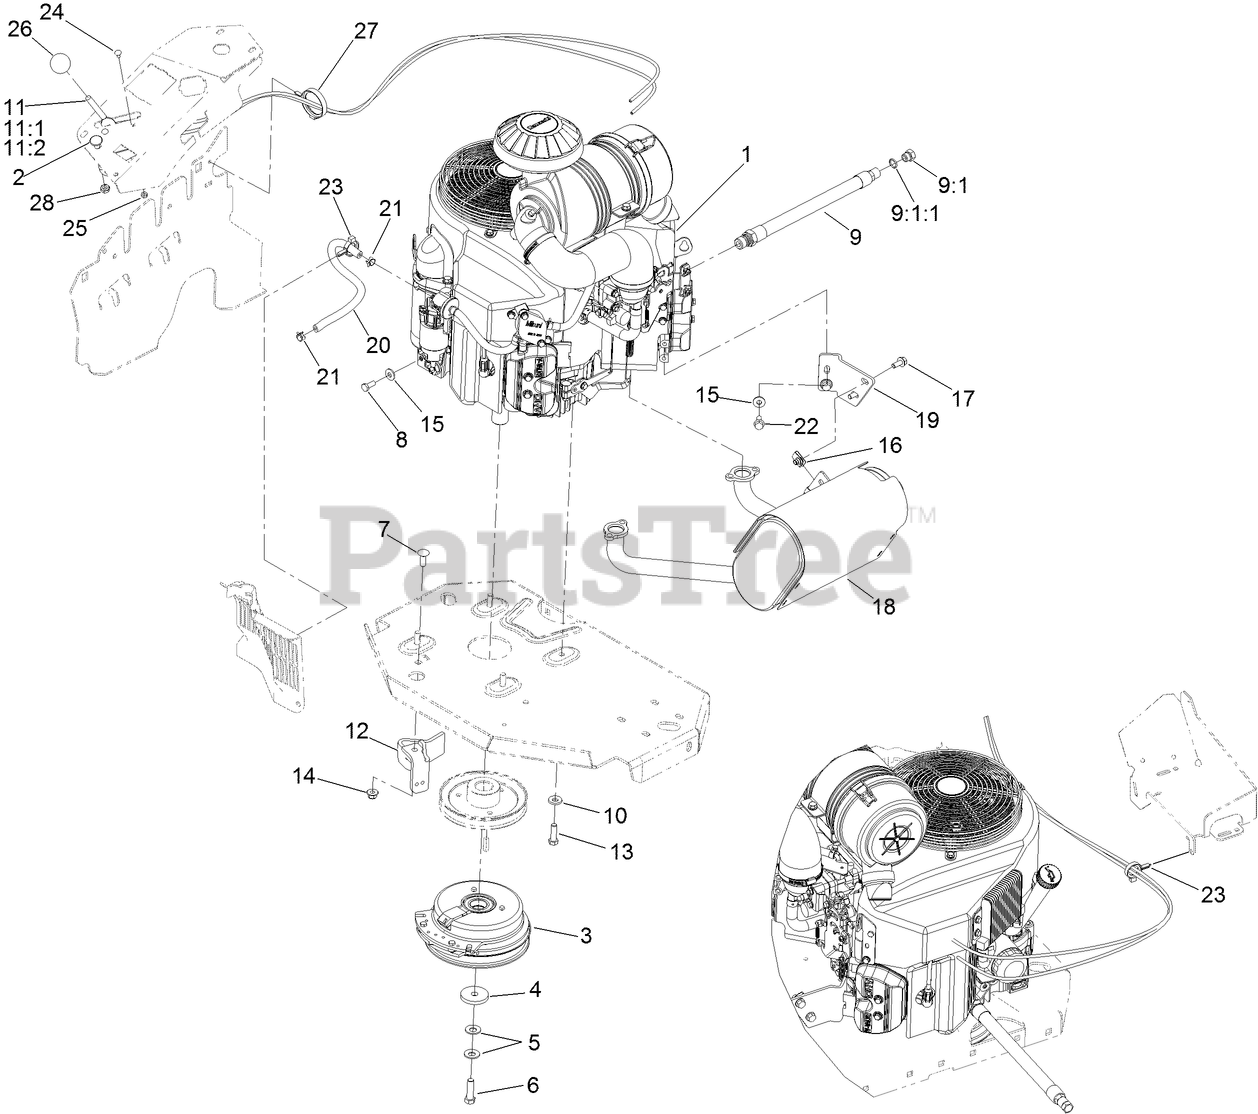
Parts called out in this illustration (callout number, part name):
2	CONTROL-CHOKE
3	CLUTCH KIT
4	WASHER-CLUTCH
5	WASHER-SPRING
6	SCREW-HH, W/LOCTITE
7	SCREW-CARR
8	SCREW-HH
9	ENGINE OIL DRAIN HOSE ASM
9:1	PLUG-HH
9:1:1	O-RING
10	WASHER-BELLEVILLE
11	THROTTLE CONTROL ASM
11:1	LEVER-THROTTLE
12	CLUTCH-ANCHOR
13	SCREW-HH
14	NUT-HF, NI
15	WASHER-SPRING
16	NUT-U
17	SCREW-HHF
18	MUFFLER
19	BRACKET-MUFFLER
20	HOSE-FUEL
21	CLAMP-HOSE
22	SCREW-HHF
23	CLAMP-HOSE
24	BOLT-CARR
25	NUT-LOCK, NI
26	KNOB-BALL
27	CLAMP-HARNESS
28	NUT-HJ
